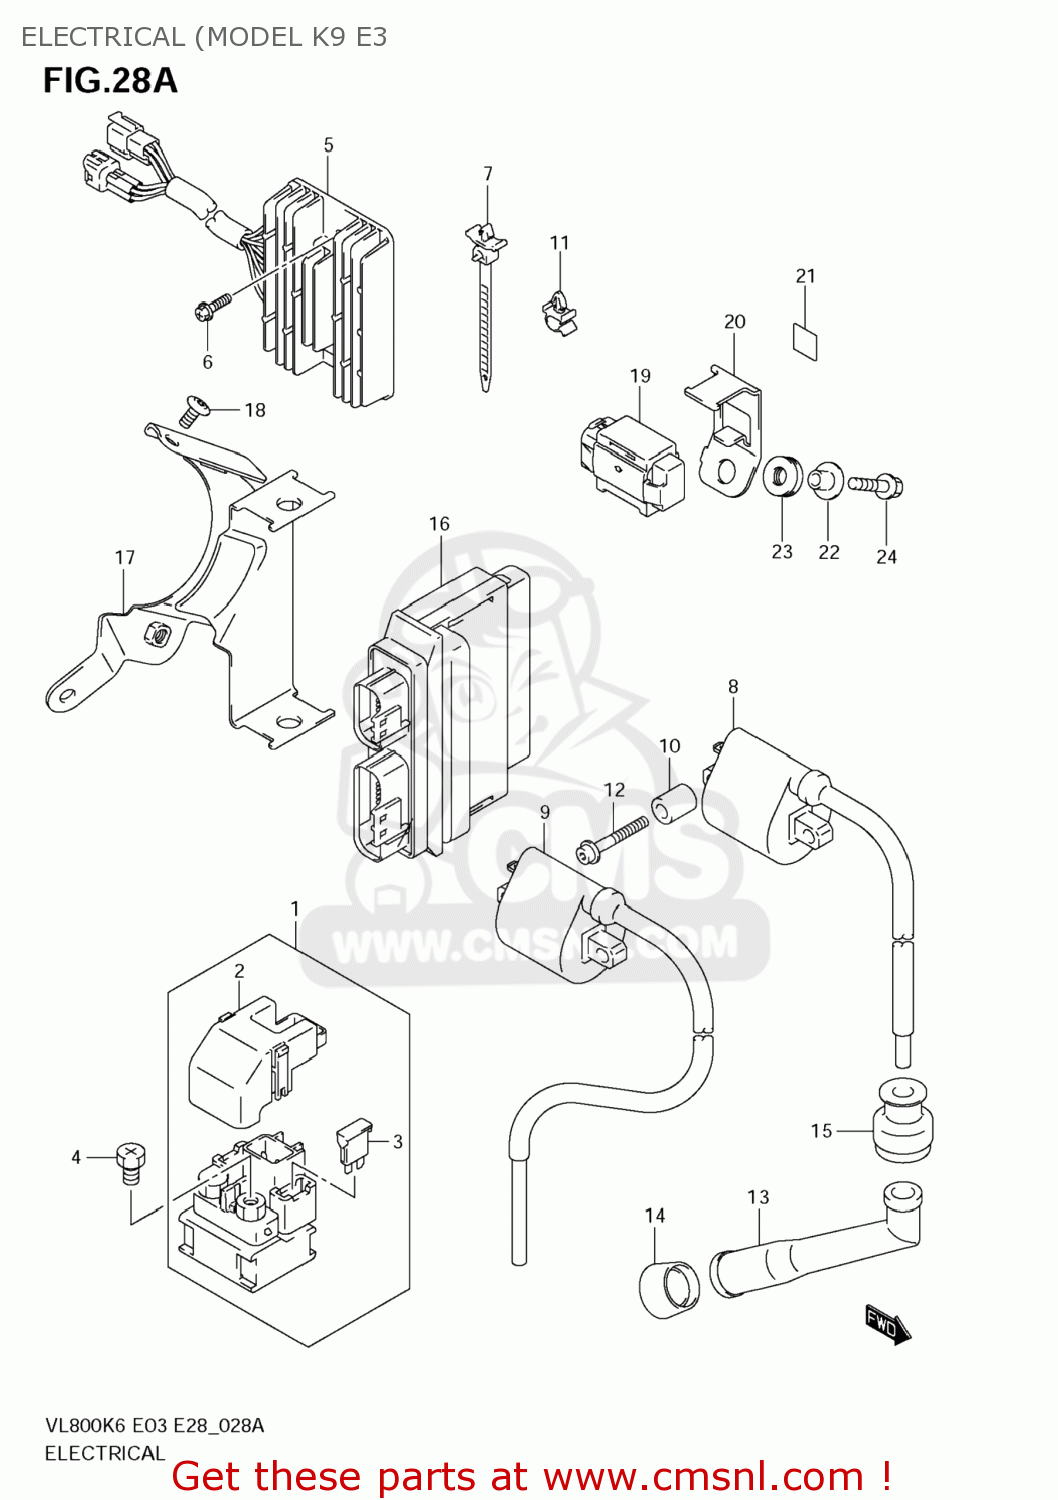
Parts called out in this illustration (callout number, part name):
1	RELAY ASSY,STARTING MOTOR
2	COVER
3	FUSE(30A)
4	SCREW(6X8)
5	RECTIFIER ASSY
6	SCREW
7	CLAMP(L:90)
8	COIL ASSY,IGNITION
9	COIL ASSY,IGNITION
10	SPACER(6.4X10X18)
11	CLAMP
12	BOLT(5X35)
13	CAP,SPARK PLUG
14	SEAL,SPARK PLUG
15	SEAL,HIGH TENSION CORD
16	CONTROL UNIT,FI
17	BRACKET,FI CONTROL UNIT
18	SCREW(6X12)
19	SENSOR ASSY,FUEL CUT
20	BRACKET,FUEL CUT SENSOR
21	CUSHION,CABLE GUIDE
22	SPACER(6.2X8.4X6.9)
23	CUSHION
24	BOLT
